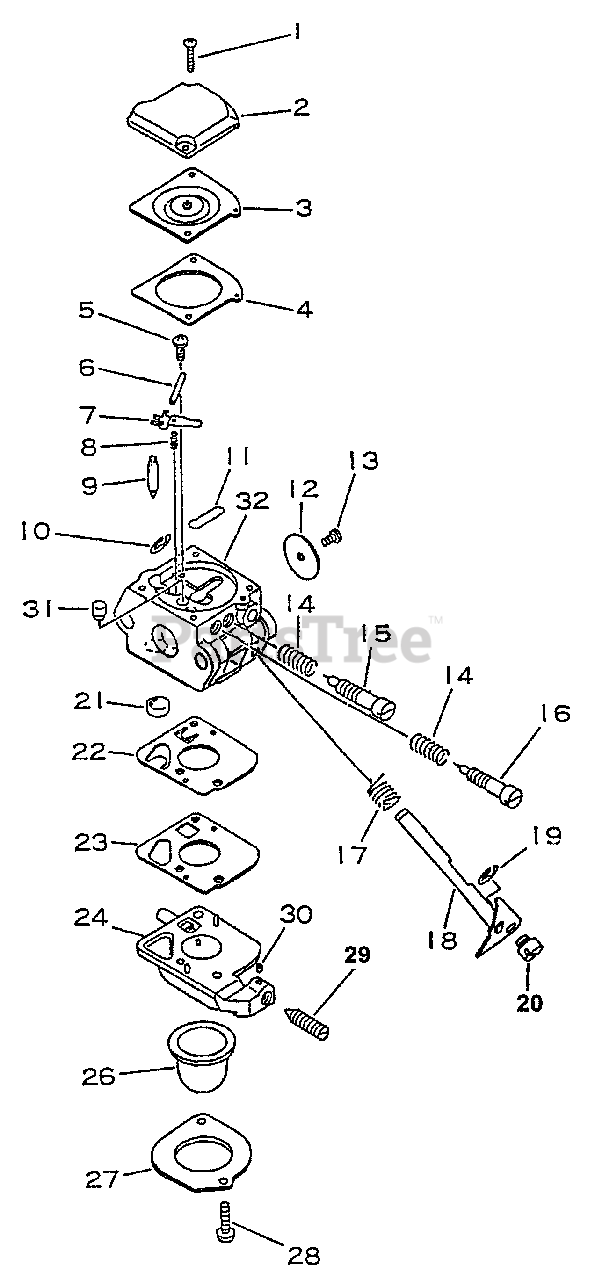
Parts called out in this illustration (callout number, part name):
2	COVER, METERING
3	DIAPHRAGM
4	GASKET, METERING
5	SCREW, METERING LEVER PIN
6	PIN, METERING LEVER
7	LEVER, METERING
8	SPRING
9	VALVE, INLET NEEDLE
10	RING, RETAINING
11	PLUG, WELCH
12	VALVE, THROTTLE
15	NEEDLE - HIGH SPEED
16	NEEDLE - MIXTURE
17	SPRING, RETURN
18	SHAFT, THROTTLE
19	RING, RETAINING
21	STRAINER
22	DIAPHRAGM, PURGE
23	GASKET, PURGE
24	BASE, PURGE
26	BULB, PURGE
27	RETAINER, PURGE BULB
28	SCREW, RETAINER
29	SCREW, IDLE ADJUST
30	PIECE, FRICTION
31	NOZZLE, CHECK VALVE
